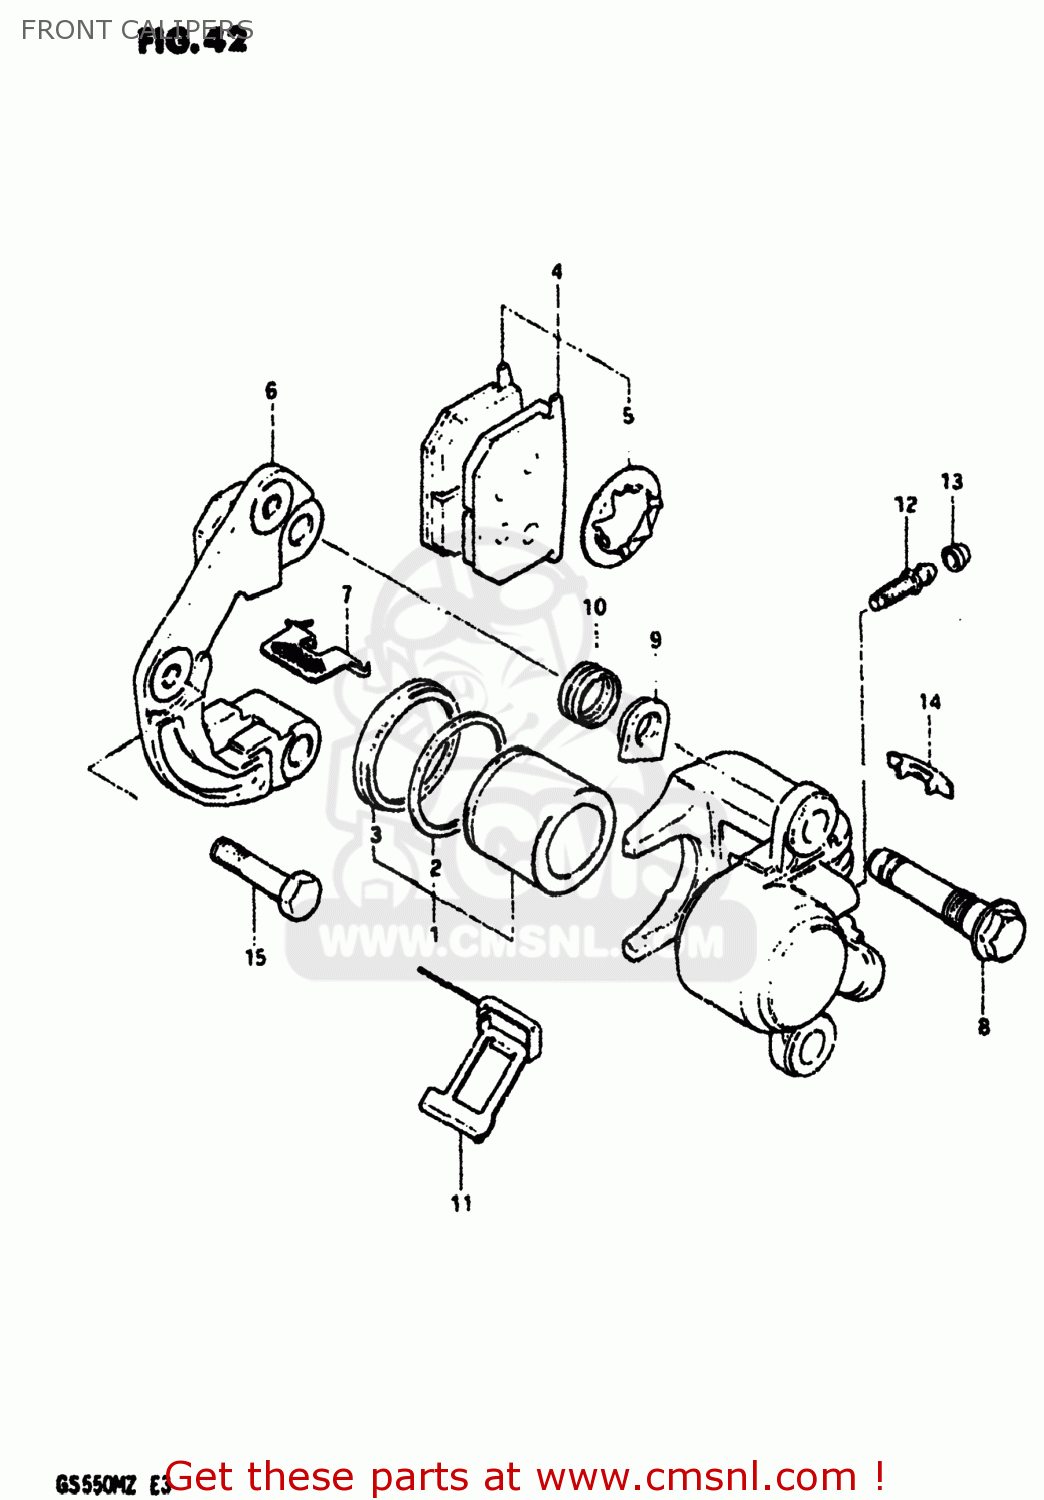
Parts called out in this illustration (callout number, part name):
0	CALIPER ASSEMBLY,FRONT,LEFT
1	PISTON SET
2	SEAL,PISTON
3	BOOT,PISTON
4	PAD & SHIM SET (MCA)
5	SHIM,PAD
6	HOLDER,CALIPER,LEFT
7	PAD,GUIDE
8	AXLE,CALIPER
9	NUT,CALIPER AXLE
10	BOOT
11	SPRING
12	BREATHER
13	CAP,BLEEDER PL
14	COVER,INDICATOR
15	BOLT 10X37
